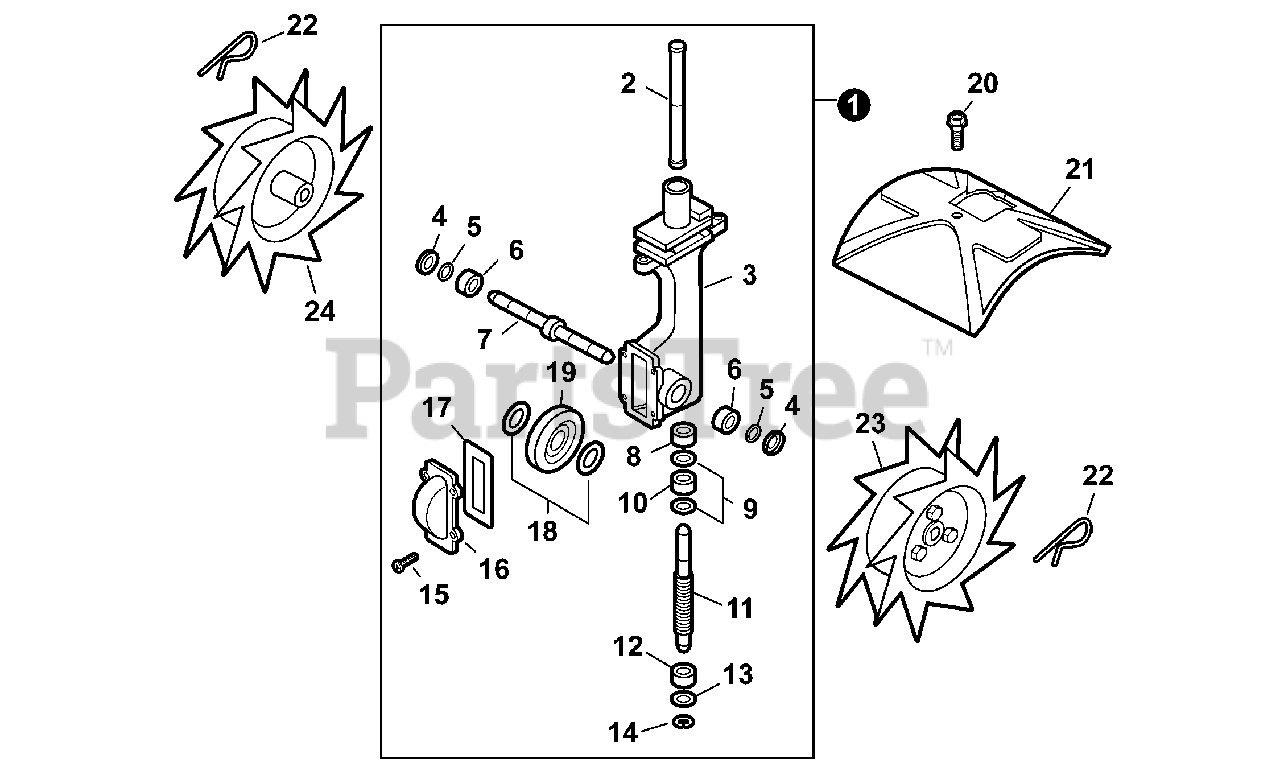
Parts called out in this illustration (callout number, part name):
1	GEAR CASE ASSY
2	SHAFT, DRIVE
3	CASE, GEAR
5	RETAINER
6	BEARING, NEEDLE
8	BEARING, NEEDLE
10	BEARING, THRUST
11	GEAR, WORM
12	BEARING, ROLLER
14	RING, RETAINING
15	SCREW, TAPPING
16	COVER, GEAR CASE
17	GASKET, GEAR CASE
18	WASHER, THRUST 8
19	GEAR, WORM
20	BOLT 1/4×1/2
21	SHIELD, DEBRIS
22	PIN, SNAP
23	TINE, RIGHT
24	TINE, LEFT
